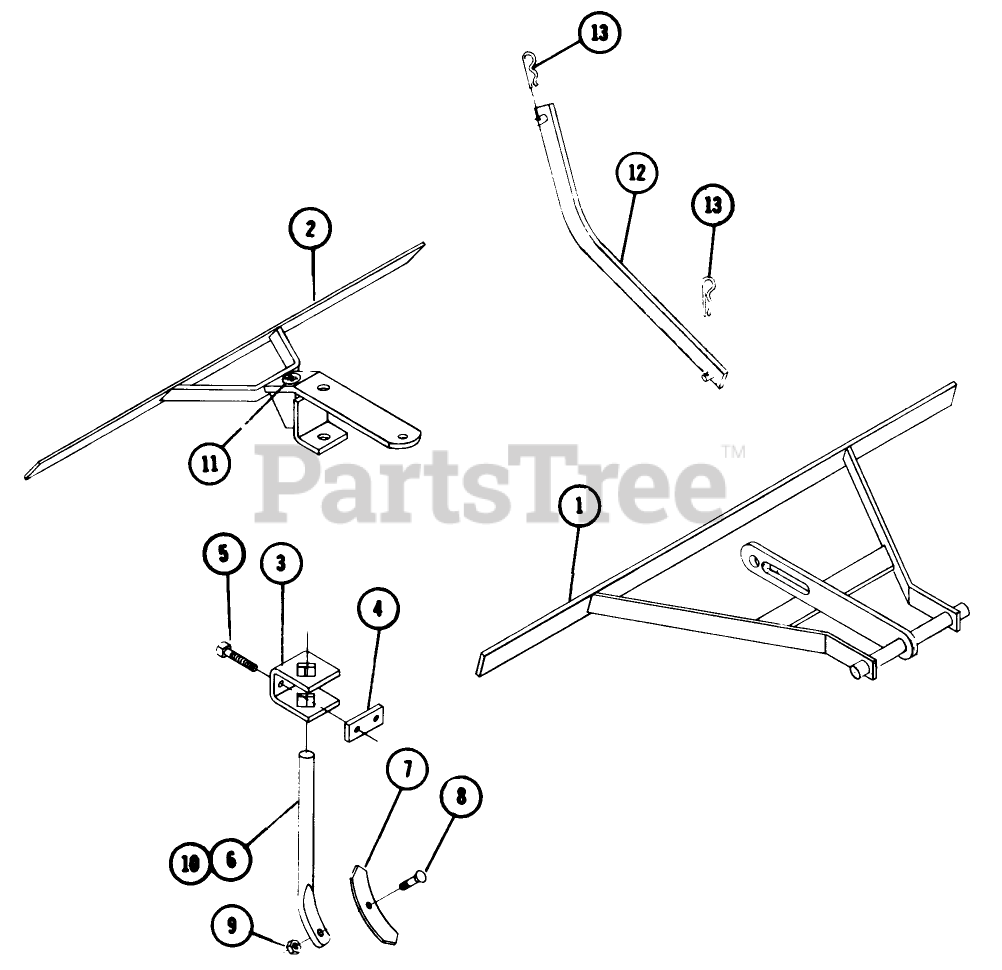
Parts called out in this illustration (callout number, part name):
1	Frame Assembly-Front
2	Frame Assembly-Rear
3	Clamp
4	PLATE
5	SQ HD CUP POINT SCR
6	Standard
7	Shovel
8	PLOW BOLT
9	Nut
10	STANDARD SHOVEL
11	DECAL-WHEEL HORSE
